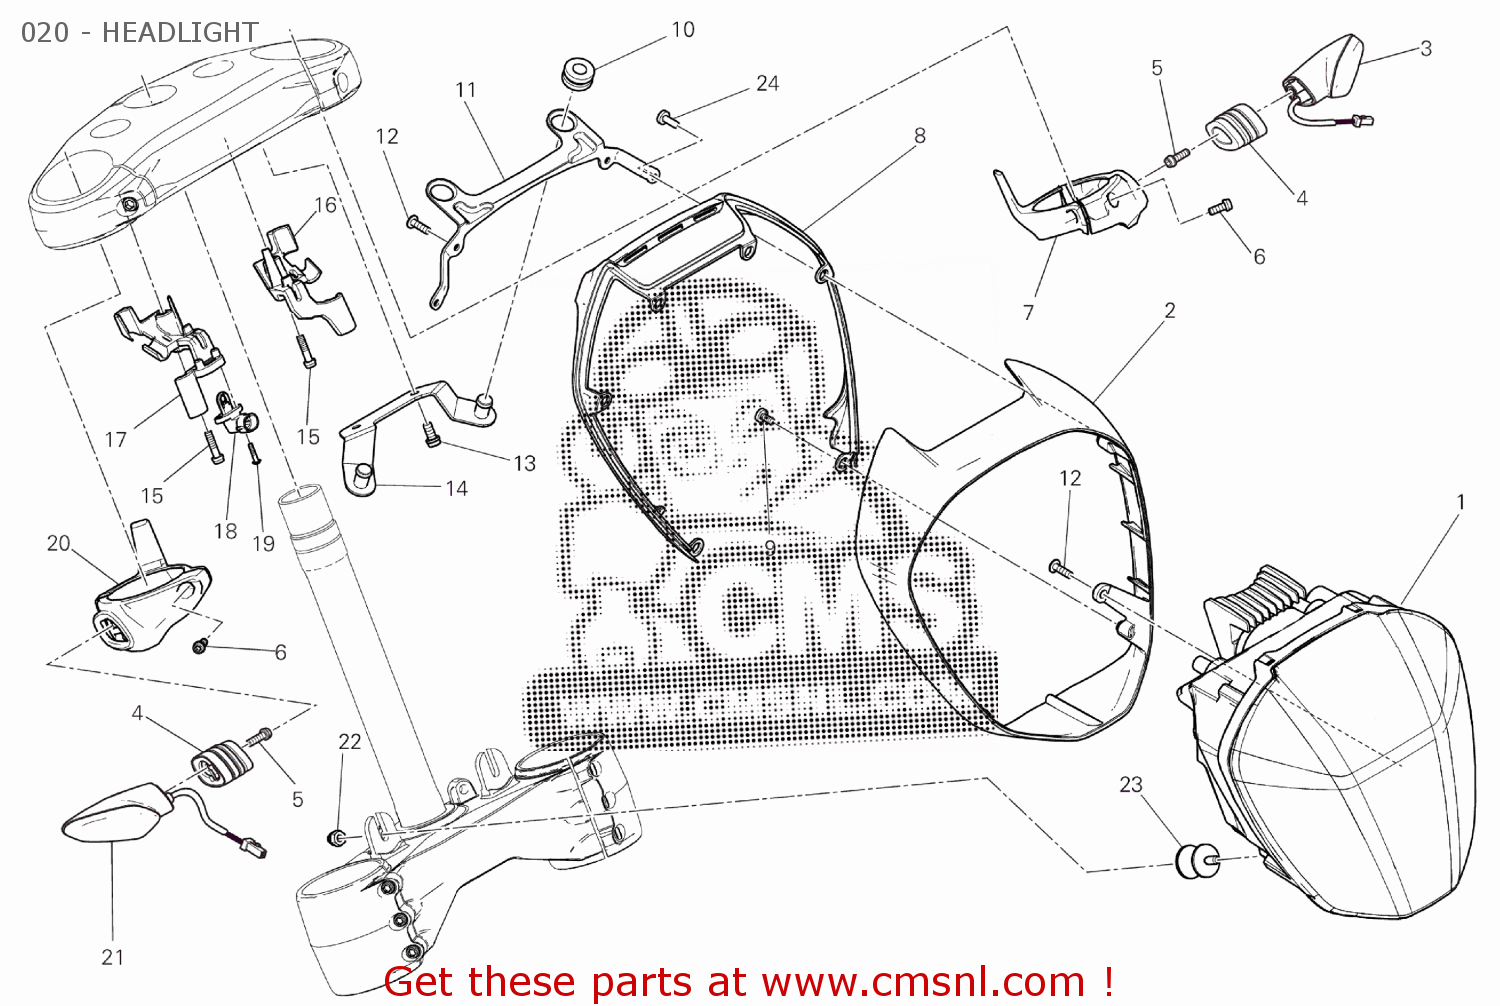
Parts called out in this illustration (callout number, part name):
1	HEADLIGHT
2	BRACKET, HEADLIGHT
3	FLASHER LIGHT FRONT LH - REAR RH
4	SPACER
5	SCREW TCEIF M5X16
6	SCREW M5X12
7	BRACKET, LEFT FLASHER LIGHT
8	COVER
9	SCREW TBEI M5X10
10	VIBRATION DAMPER PAD
11	HEADLIGHT BRACKET
12	SCREW, TAPPING M5X16
13	SCREW TCEIF M6X14 8.8
14	BRACKET UPPER
15	SCREW
16	HOSE GUIDE
17	HOSE GUIDE
18	SENSOR, AIR TEMPERATURE
19	SCREW, TAPPING
20	BRACKET, RIGHT FLASHER LIGHT
21	FLASHER LIGHT FRONT RH- REAR LH
22	NUT 6MM
23	DAMPER M6X12
24	SCREW M5X12
